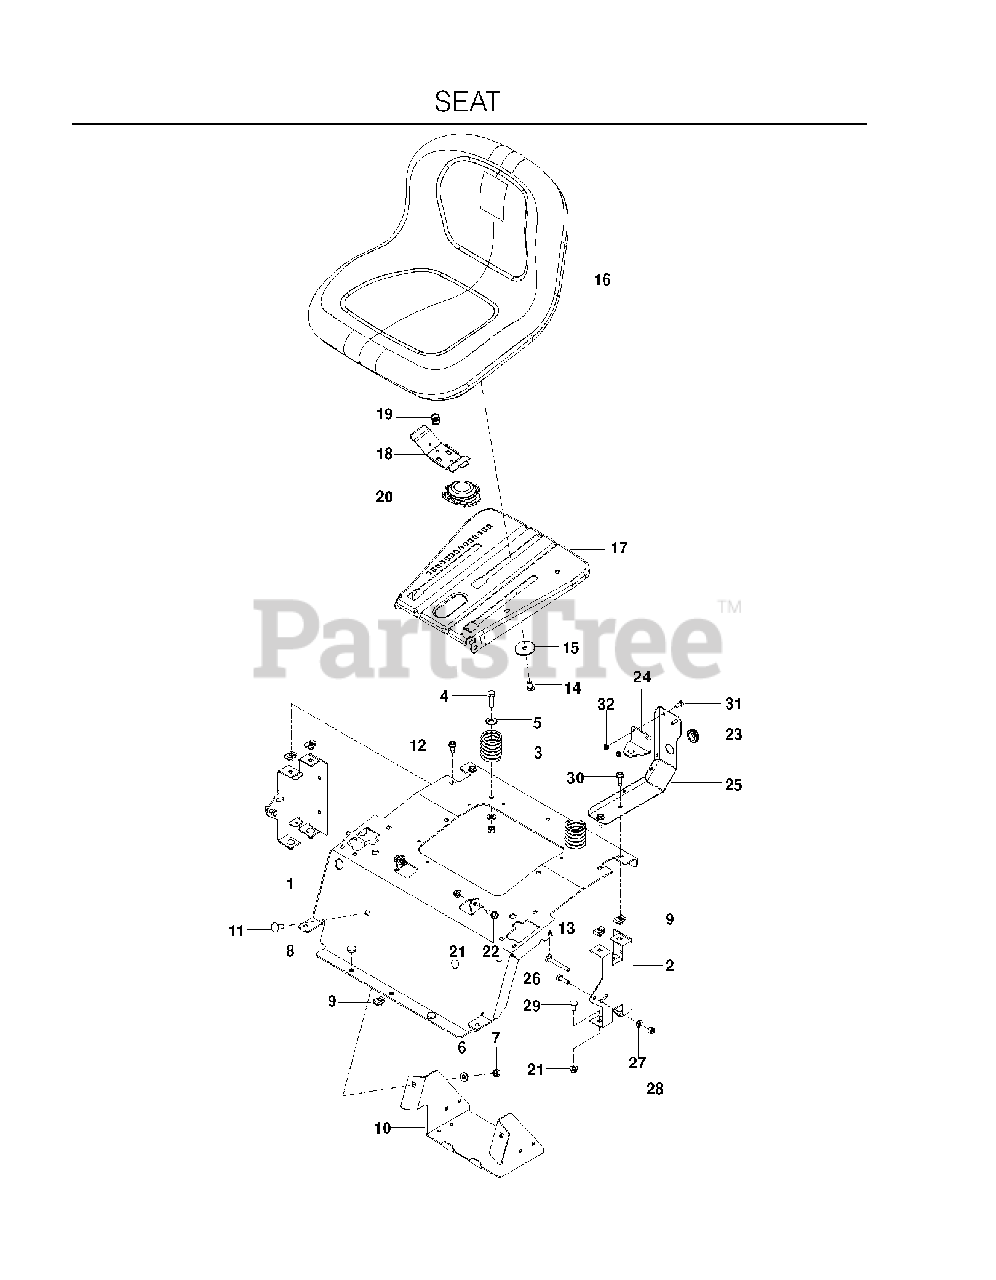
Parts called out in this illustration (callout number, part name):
1	SUPPORT, SEAT, BLUE
2	SUPPORT REAR SEAT BLA
3	SPRING, SEAT
4	HCS 3/8C X 1 1/4 GR5
5	WASHER 3/8 FLAT
6	WASHER 3/8 SAE FLAT
7	NUT 3/8-16 NYLOC
8	GROMMET, BUMPER
9	U-CLIP 5/16-18 NUT RETAINER
10	BOX, BATTERY, BLACK
11	RHSNB 3/8C X 1
12	BOLT 5/16-18 X 3/4
13	RHSNB 5/16-18 X 2-1/2 GR5 ZD
14	HCS 3/8-16 X 5/8 GR 5 ZD
15	WASHER, 3/8 SPEC
16	SEAT,BLACK W/ARMREST PROVISION
17	PAN.ASM.SEAT.3PT
18	HANDLE.SLIDE.SEAT.TEX.BLACK
19	SPRING.LATCH.SEAT.TEX
20	SWITCH, SEAT N/C
21	5/16-18 NYLOC FLANGE NUT
22	BOLT, SHOULDER
23	GROMMET, FUEL LINE
24	BRACKET, VALVE BLK
25	MOUNT, VALVE BLK
26	HCS 5/16C X 1
27	FLAT WASHER 5/16 SAE
28	NUT 5/16 NYLOC
29	BOLT 5/16C X 3/4" CARRIAGE
30	Hex Washer Head Bolt, 5/16-18 X 3/4 Thread Forming
31	HCS 1/4-20 X 5/8 COATED GR5 ZD
32	JAM NUT 1/4C
